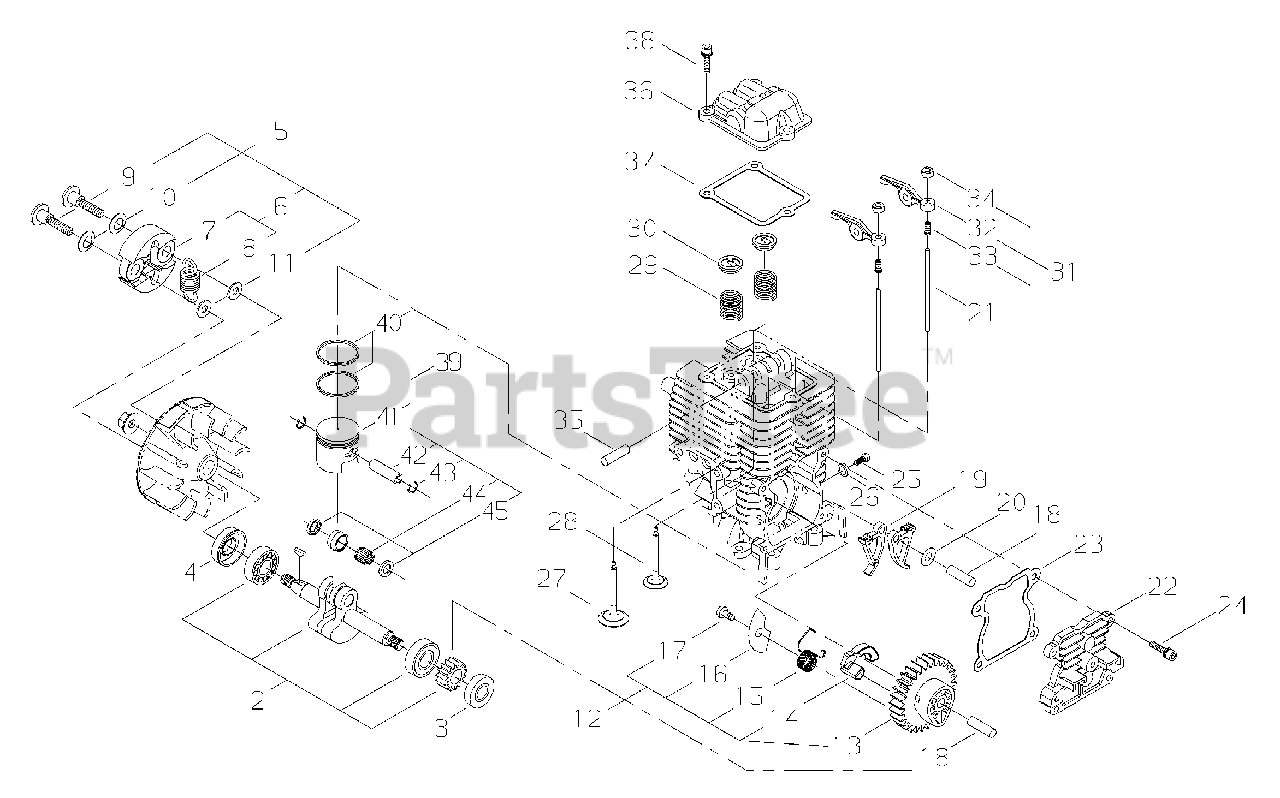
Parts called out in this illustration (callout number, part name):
2	CRANKSHAFT ASSY
3	SEAL, OIL 12
4	SEAL, OIL 12
5	CLUTCH ASSY
6	SHOE ASSY, CLUTCH
7	SHOE, CLUTCH
8	SPRING, CLUTCH
9	BOLT, CLUTCH
10	WASHER, SPRING
11	WASHER 6 MM
12	CAM GEAR ASSY
13	GEAR, CAM
14	WEIGHT
15	SPRING
16	PLATE
17	SCREW, TAPPING 4×6
18	PIN, LOCATING Ø5×29.8 MM
19	FOLLOWER, CAM
20	WASHER 5 MM
21	PUSHROD
22	COVER, CAM GEAR
23	GASKET, CAM GEAR
24	BOLT M4×14
25	SCREW M5
26	WASHER Ø10ר5.5×2
27	VALVE, INTAKE
28	VALVE, EXHAUST
29	SPRING, VALVE
30	VALVE RETAINER ASSY
31	ARM ASSY, ROCKER
32	ARM, ROCKER
33	SCREW, ADJUSTER
34	NUT, ADJUSTER LOCK 5
35	SHAFT, ROCKER ARM Ø5×37.8 MM
36	COVER, ROCKER ARM
37	GASKET, ROCKER ARM
38	BOLT M4×14
39	PISTON KIT
40	RING, PISTON
41	PISTON
42	PIN, PISTON 10
43	RING, SNAP
44	BEARING, NEEDLE 10
45	WASHER, THRUST 10
